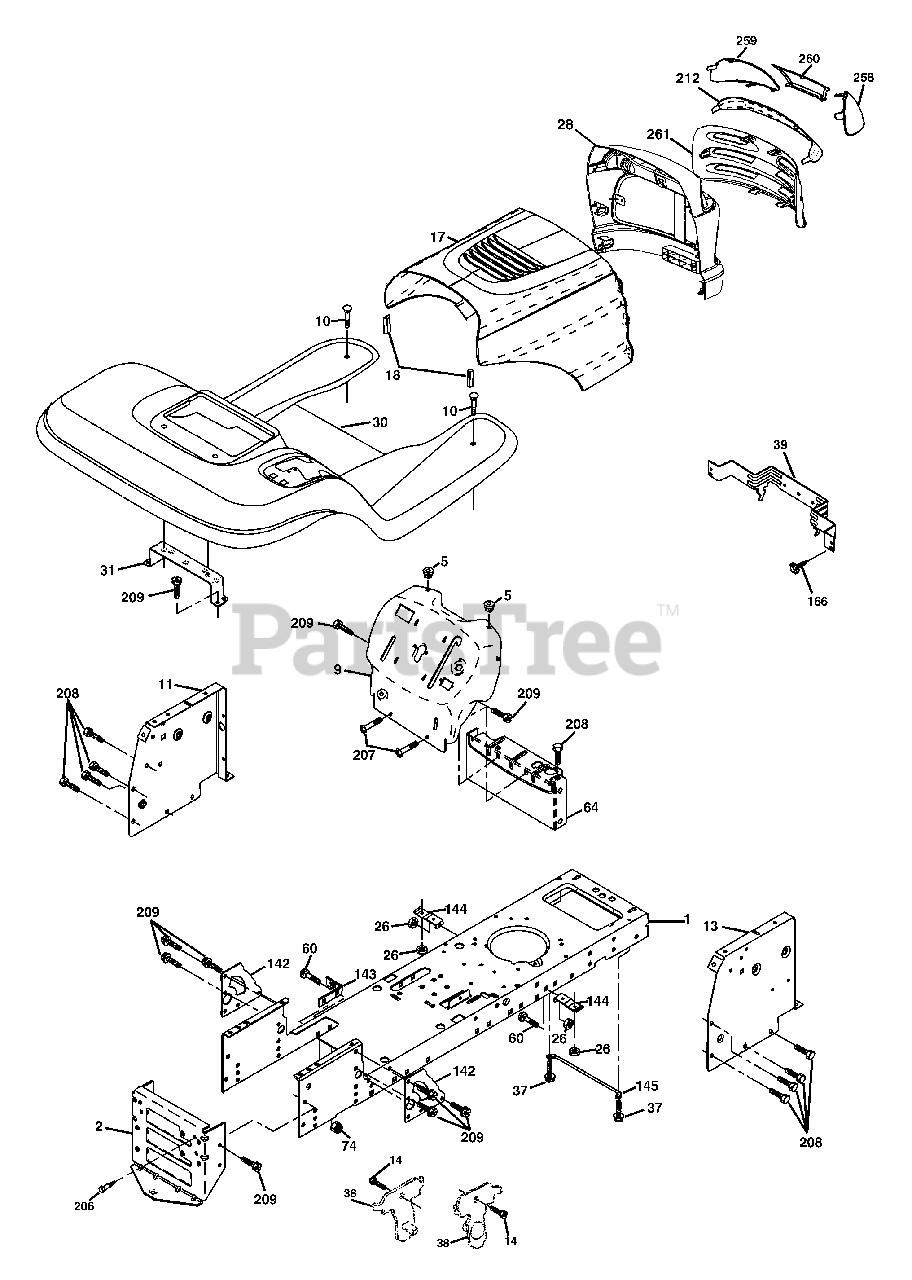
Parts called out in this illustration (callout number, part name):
1	Chassis Stamping
9	Dash
10	Bolt Rdhd Sqnk 3/8-16 unc x 1
11	Panel Dash Lh
13	Panel Dash Rh
14	Screw Thdrol 3/8-16 x 1/2
17	Hood
18	Bumper Hood
26	Nut Lock w/Insert 3/8-16 unc
28	Grille Lens Asm
30	Fender
37	Screw Thdrol 5/16-18 x 1/2
38	Bracket Asm Pivot Mower Rear
39	Bracket Pivot Hood
60	Bolt RDHD SQNK 3/8-16 x 3/4
64	Dash Lower Stlt
74	Nut Crownlock 3/8-16
142	Plate Reinforcement Stlt
143	Bracket Swaybar Chassis
144	Bracket Ft Rest
145	Rod Pivot Chassis Hood
166	Screw Hw Hd Hi-Lo #13-16 x 3/4
206	Bolt Shoulder 5/16-18 TT
207	Screw Thdrol 5/16-18 x 1/2 TYTT
208	Screw Thdrol 3/8-16 x 1/2 TY-TT
209	Screw 3/8-16 x 3/4
212	Insert Lens Reflect
258	Lens RH
259	Lens LH
260	Cover Lens
261	Insert, Grille
